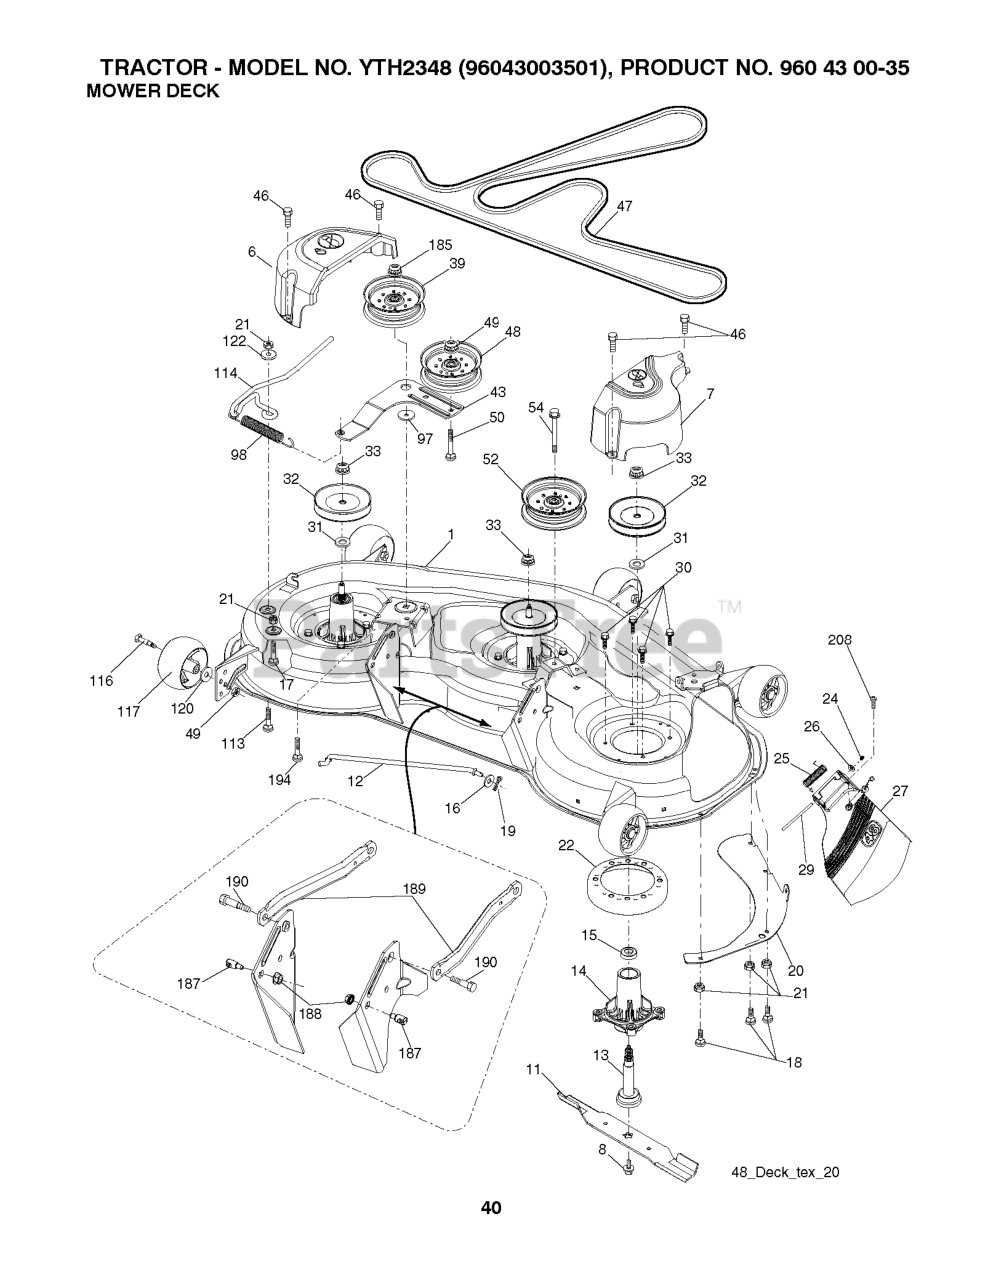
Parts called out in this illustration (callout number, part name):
1	DECK.PNT.WELDMENT.48"T
6	COVER.MANDREL.LH.48"(2 2)
7	COVER.MANDREL.RH.48"
8	BOLT 7/16 ASM BLADE
11	48" HI-LIFT BLADE
12	ROD.ANTI.SWAY.48/54"K4
13	SHAFT ASM MANDREL
14	RP.HOUSING.MANDREL.4PT.
16	WASHER
17	BOLT.CARR.5/16-18X5/8.SHORT
18	BOLT
19	PIN.COTTER.5/16.BOW TI
20	BAFFLE, VORTEX MWR
21	LOCKNUT
22	STRIPPER.MANDREL.ROUND.BLACK
24	CAP-SLEEVE LT
25	SPRING, TORSION
26	NUT PUSH M
27	DEFLECTOR SUBS TO 532 180655
29	ROD.HINGE
30	SCREW, WASHER HEAD
31	WASHER.SPACER.MANDREL
32	PULLEY MANDREL
33	NUT.FLANGE.LOCK.TOP
39	RB PULLEY.IDLER.4.50/HUB SPEC
43	ARM.IDLER
46	SCREW.1/4-20X5/8
47	BELT.DRIVE.DECK
48	PULLEY.IDLER.48"PRIMARY
49	NUT LOCK FLG 3/8-16 UNC
50	SCREW TT 3/8-16X2-1/4 UNC
52	PULLEY.IDLER.2006
54	BOLT.3/8-16X1.50
98	SPRING, DECK DRIVE
113	BOLT CRT
114	ROD.TENSION.RELIEF.TEX (2 2)
116	BOLT.SHOULDER.3/8-16X3-5/8.
117	RP WHEEL. GUAGE RALLY
120	WASHER
122	BUSHING.RELIEF.TENSION
185	NUT.LOCK.FLANGE.7/16
187	STUD.FASTNER.W/ANTI-ROTATE
188	NUT LOCK HEX FLANGE 5/16-18
189	ARM.SUSPENSION.MOWER
190	BOLT.SHOULDER
194	BOLT.CARR.SQNK.7/16
208	SCREW 3/8-16X1/2
